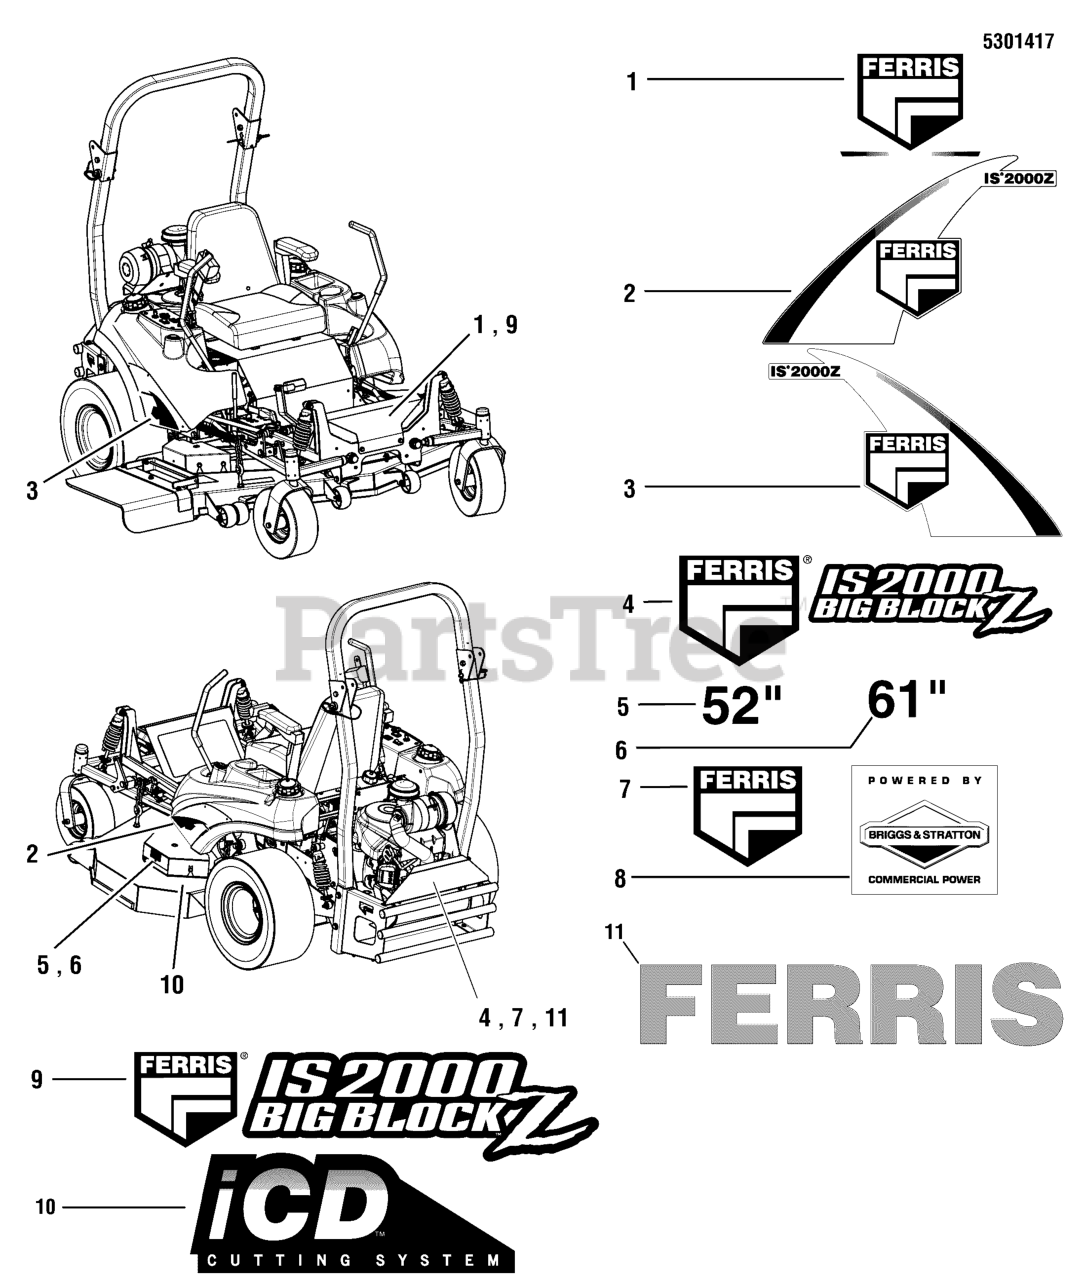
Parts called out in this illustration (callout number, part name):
2	DECAL, BADGE, IS2000Z, LH
3	DECAL, BADGE, IS2000Z, RH
4	DECAL, 2000, BIG BLOCK, REAR
5	DECAL, 52
6	DECAL, 61"
9	DECAL, 2000, BIG BLOCK, FRONT
10	DECAL, iCD CUTTING SYSTEM
11	DECAL, FERRIS, 2.23" X 11.39"
